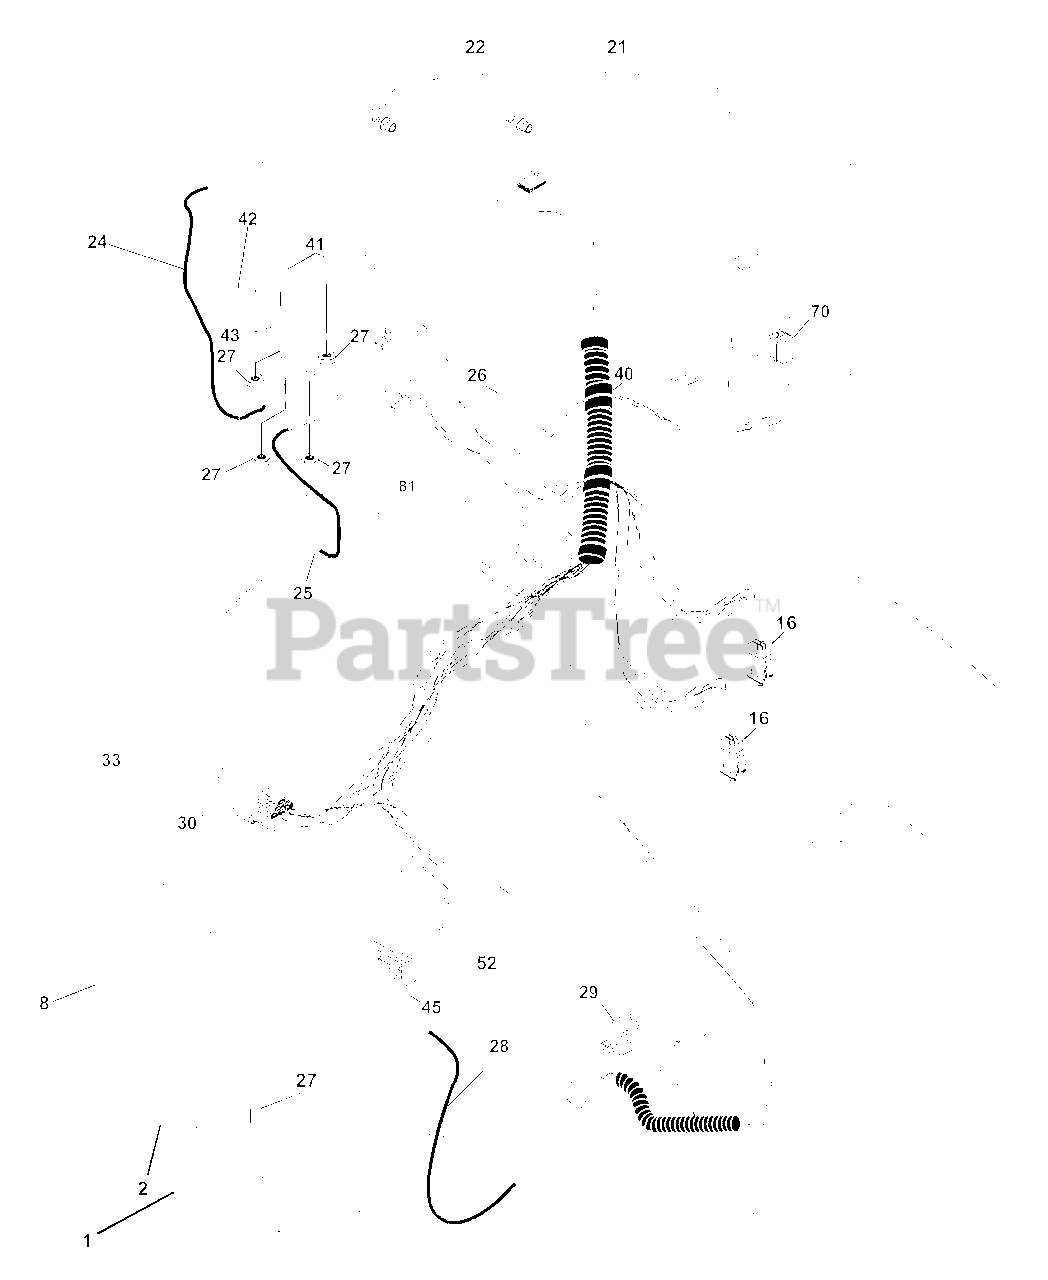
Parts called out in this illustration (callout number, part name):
1	Battery
2	Bolt Hex Hd 1/4-20unc X 3/4
8	Case Battery Mech Hinge
16	Switch Interlock Push-In
21	Harness Socket Light
22	Bulb, Light # 1156
24	Cable Battery
25	Cable Battery 6 Ga Red w/16 wire
26	Fuse 15 Amp
27	Nut Keps Hex 1/4-20 Unc
28	Cable Ground 6ga 12 black
29	Switch Plunger Nc Olive
30	Switch Ign
33	Key Ign Molded Generic
40	Harness Ign
41	Bolt Fin Hex 1/4-20unc x 1/2
42	Cover Terminal Red
43	Solenoid
45	Ammeter Rectangular
52	Protection Loop
70	Harness Engine Tec/Kohl Regula
81	Relay Asm
